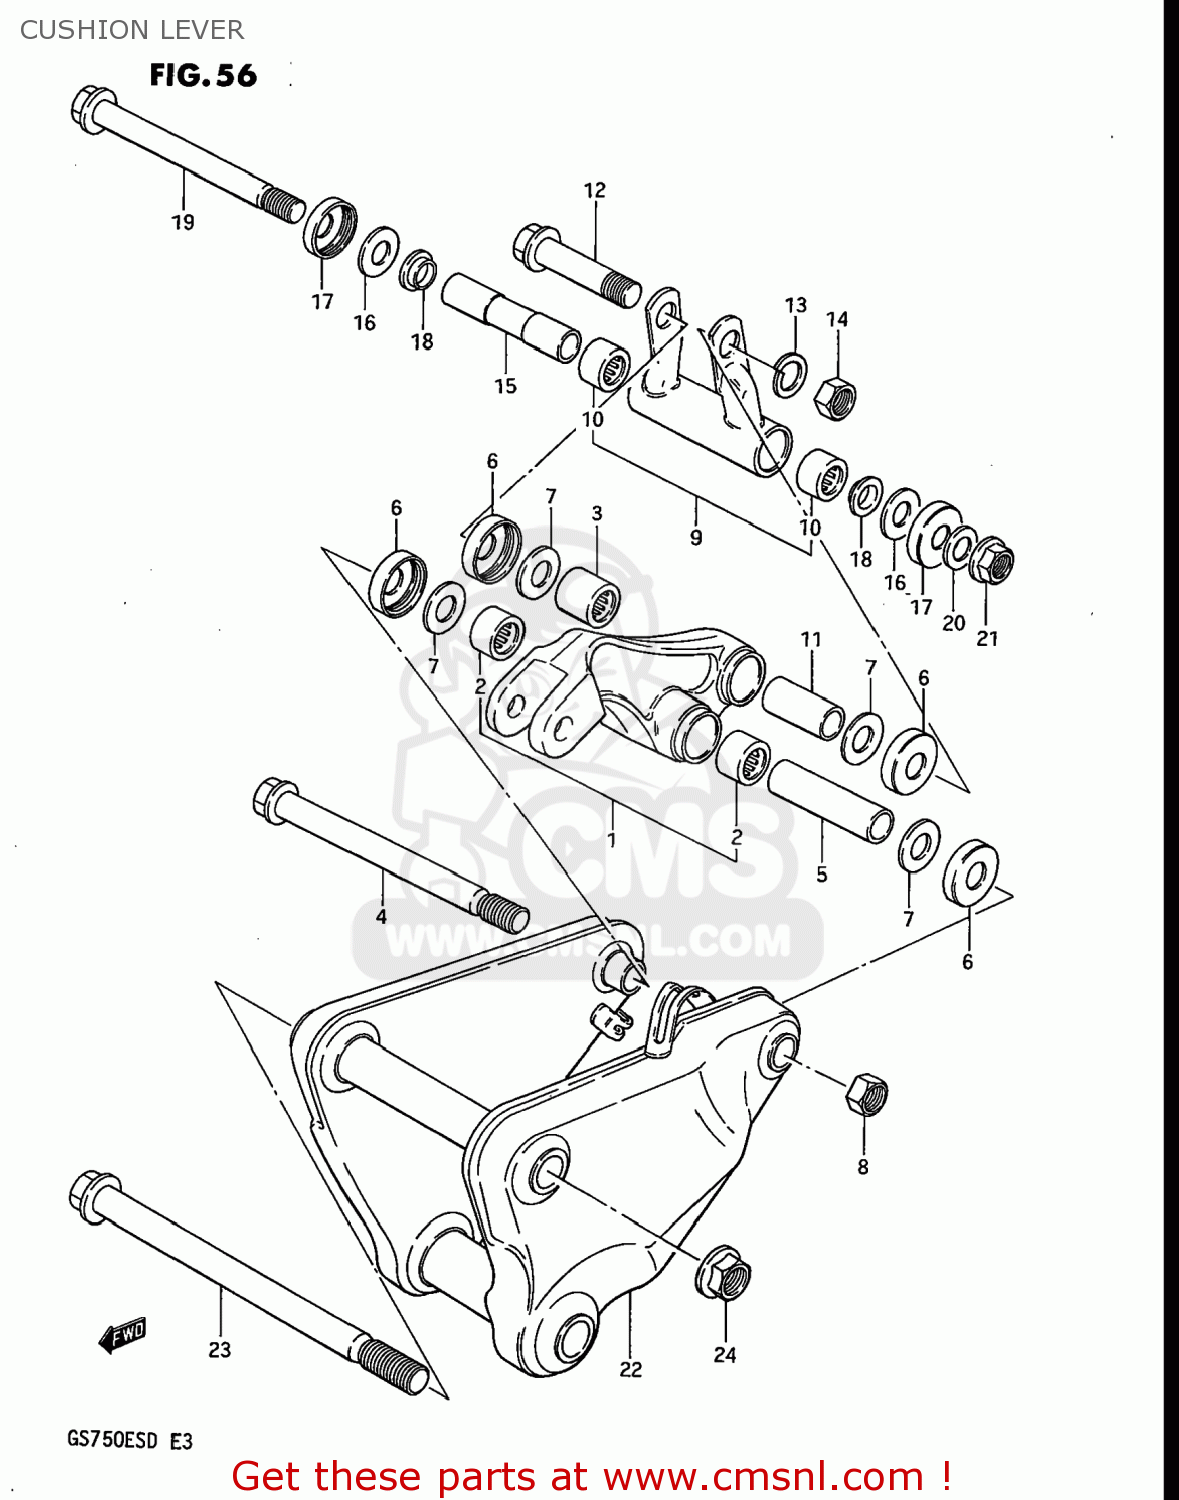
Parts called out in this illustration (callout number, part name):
1	LEVER SET,REAR CUSHION
2	ROLLER BEARING (17X24X2
3	ROLLER BEARING (17X24X25)
4	SHAFT,RR CUSHION LEVER
5	SPACER,REAR CUSHION LEVER
6	COVER,RR SWGARM DUST SEAL
7	WASHER
8	NUT
9	ROD SET,CUSHION
10	ROLLER BEARING (17X24X2
11	SPACER,RR CUSHION LEVER ROD UP
12	BOLT, UPPER
13	WASHER,LOCK 12
14	NUT
15	SPACER,RR CUSHION LVR ROD LOW
16	WASHER
17	COVER,RR SWGARM DUST SEAL
18	SPACER,REAR CUSHION ROD
19	BOLT,CUSHION ROD
20	WASHER
21	NUT
22	BRACKET,REAR SHOCK ABSORBER
23	SHAFT,SHOCK ABSORBER BRACKET
24	NUT
